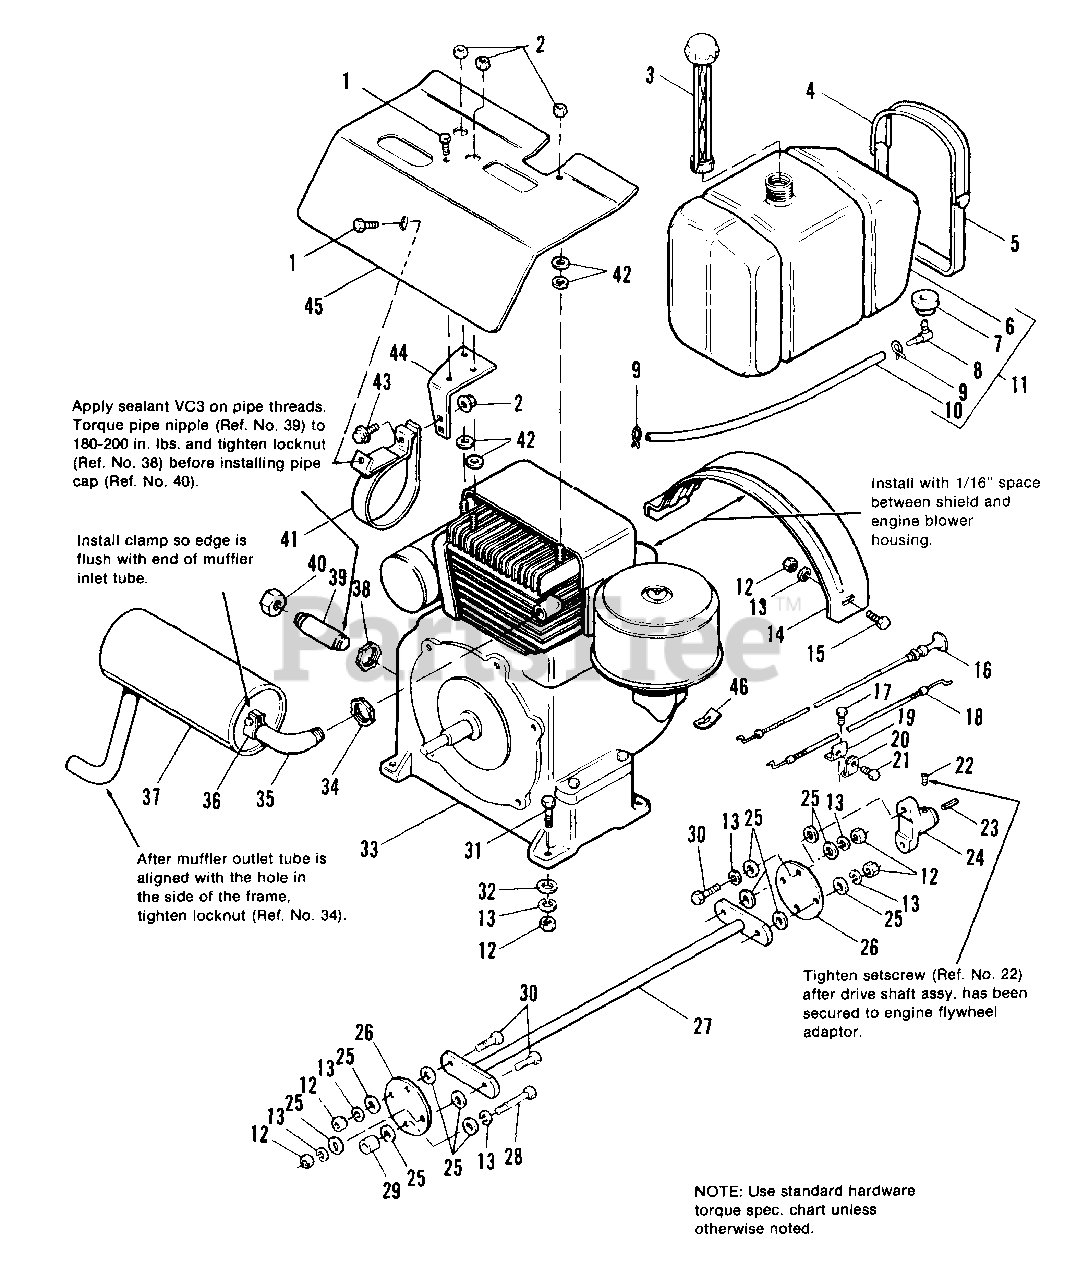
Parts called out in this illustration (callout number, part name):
1	SCREW, Hex, Taptite, 1/4-20 x 1/2
2	NUT, Hex, Whizlock, 5/16-18
3	CAP, Fuel Tank
4	STRAP, Fuel Tank
5	STRAP, Fuel Tank
11	TANK ASSY., Fuel
12	NUT, Hex, Full, 3/8-16
13	LOCKWASHER, 3/8
15	CAPSCREW, Hex Hd., 3/8-16 x 3/4
16	CONTROL, Choke
17	SCREW, Hex Hd., Type F, 1/4-20 x 5/8
18	CONTROL, Throttle
19	BRACKET, Cable
20	CLIP, Bowden Wire
21	SCREW, Hex, Taptite, #10-24 x 1/2
22	SETSCREW, 3/8-24 x 3/8
23	KEY, Drive Shaft
24	FLANGE, Drive Shaft
25	WASHER, Special
27	SHAFT ASSY., Drive
28	CAPSCREW, Hex Hd., 3/8-16 x 2-1/4
30	CAPSCREW, Hex Hd., 3/8-16 x 1-1/4
31	CAPSCREW, Hex Hd., 3/8-16 x 1-1/2
32	WASHER, Piain, 3/8
33	ENGINE, 14 HP Briggs & Stratton ENGINE, 16 HP Briggs & Stratton
35	ELBOW ASSY., Exhaust
36	CLAMP, Muffler
37	MUFFLER, Exhaust
38	LOCKNUT, 3/8-18
39	NIPPLE, Pipe
40	CAP, Pipe, Hex
41	STRAP ASSY., Muffler
42	WASHER, Plain, 5/16
43	CAPSCREW, Flange, Whizlock, 5/16-18 x 1-1/2
44	SUPPORT, Muffler
45	SHIELD, Heat
46	RESTRICTOR, Throttle (7114 Only)
